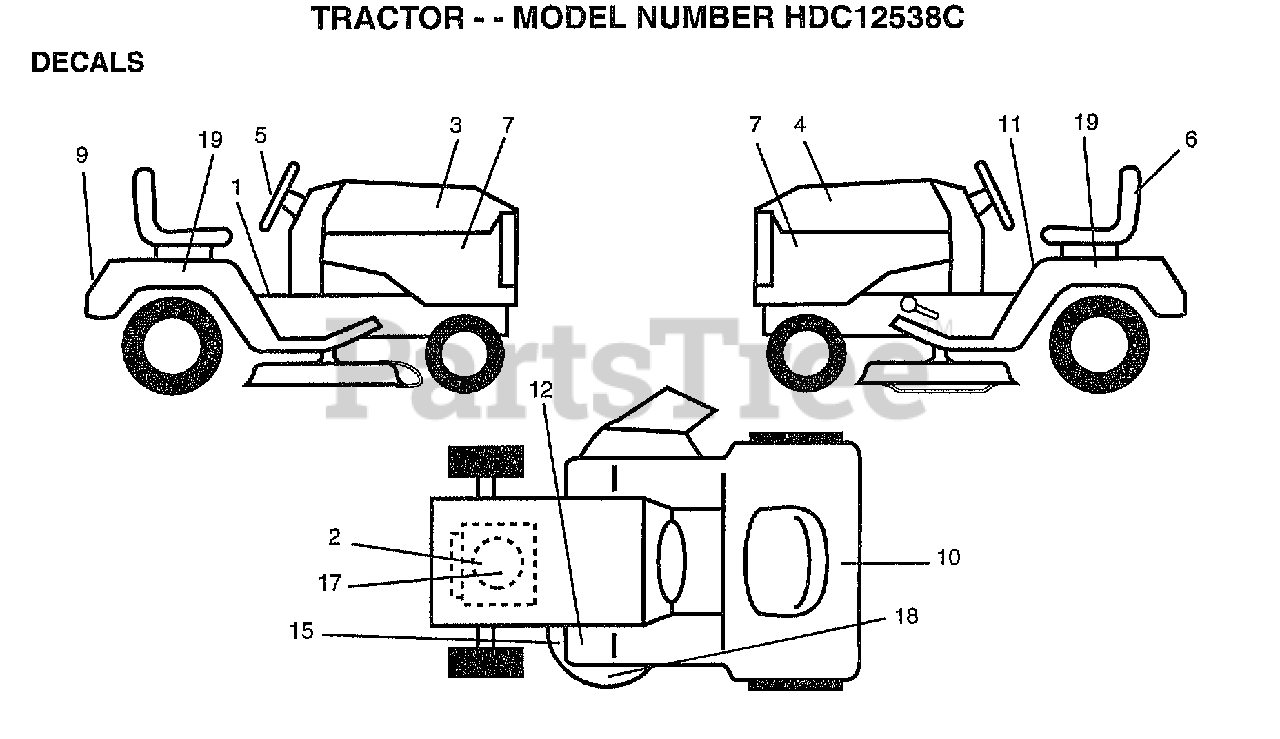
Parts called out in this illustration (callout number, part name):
2	DECAL, HP ENGINE
3	"DECAL HOOD,RH"
4	DECAL HOOD LH
5	"DECAL INS,STRG WH"
6	"DECAL SEAT,REPLCM"
7	"DECAL PENL,SIDE"
9	DECAL-FENDER
10	DECAL.BATRY.3-3908
11	"DECAL FENDER,DANG"
12	DECAL CLUT/BRAKE
15	DECAL
17	"DECAL ENGINE,REPL"
18	"DECAL MOWER,HOME"
19	"DECAL FENDER,5 SP"
